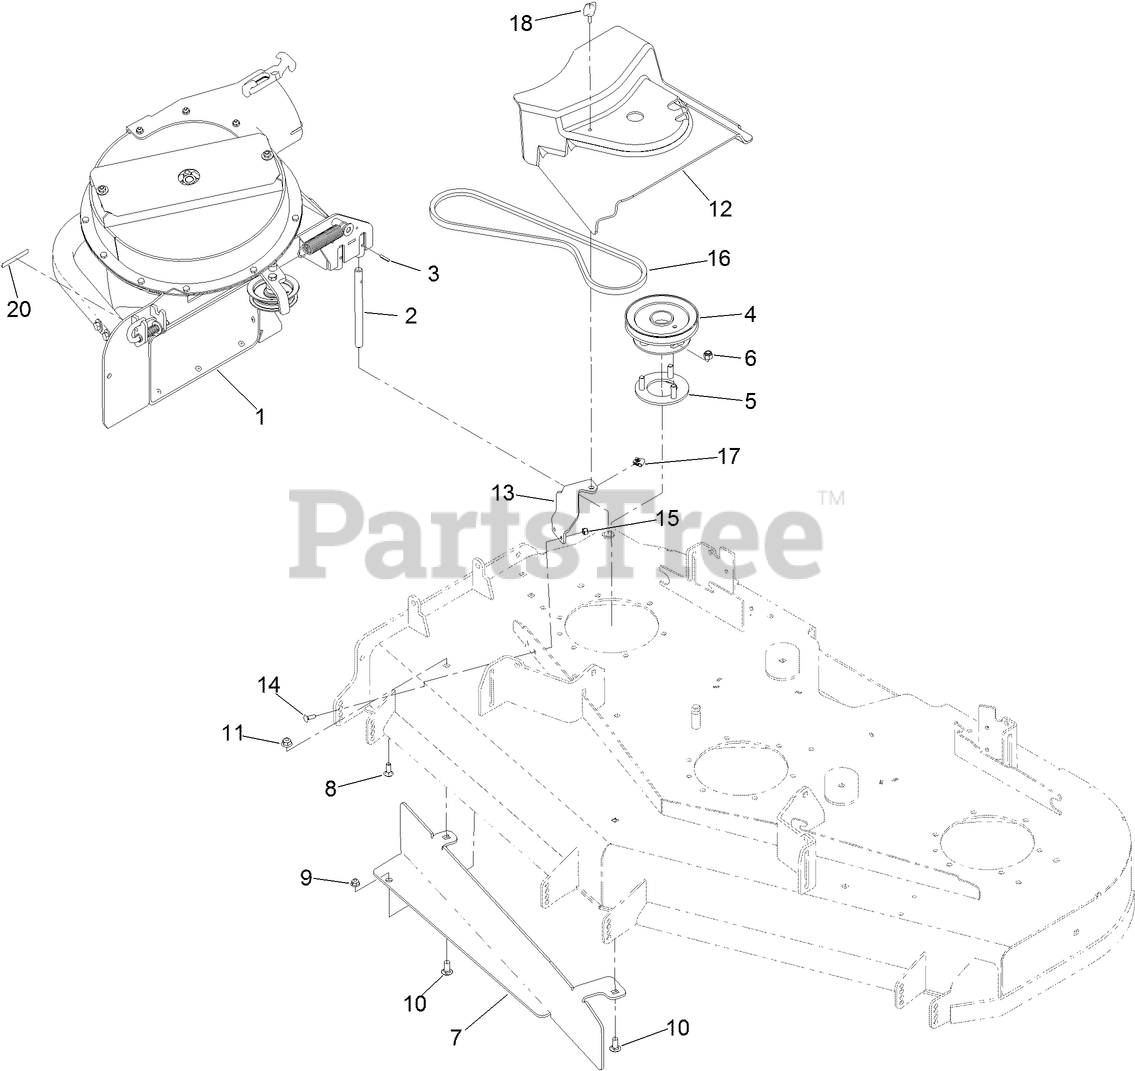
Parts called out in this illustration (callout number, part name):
1	BLOWER ASM
2	SHAFT-CATCHER, GRASS
3	PIN-ROLL
4	SHEAVE-HD60 BLOWER DRIVE
5	PULLEY MOUNT ASM
6	NUT-LOCK, NI
7	BAFFLE-BAGGER
8	SCREW-CARR
9	NUT-HF, NI
10	SCREW-CARR
11	NUT-HF, NI
12	COVER-BELT
13	BRACKET-COVER, BELT
14	BOLT-CARR
15	NUT-LOCK, NI
16	BELT-V, HITEMP
17	NUT-SPEED
20	DECAL-WARNING
